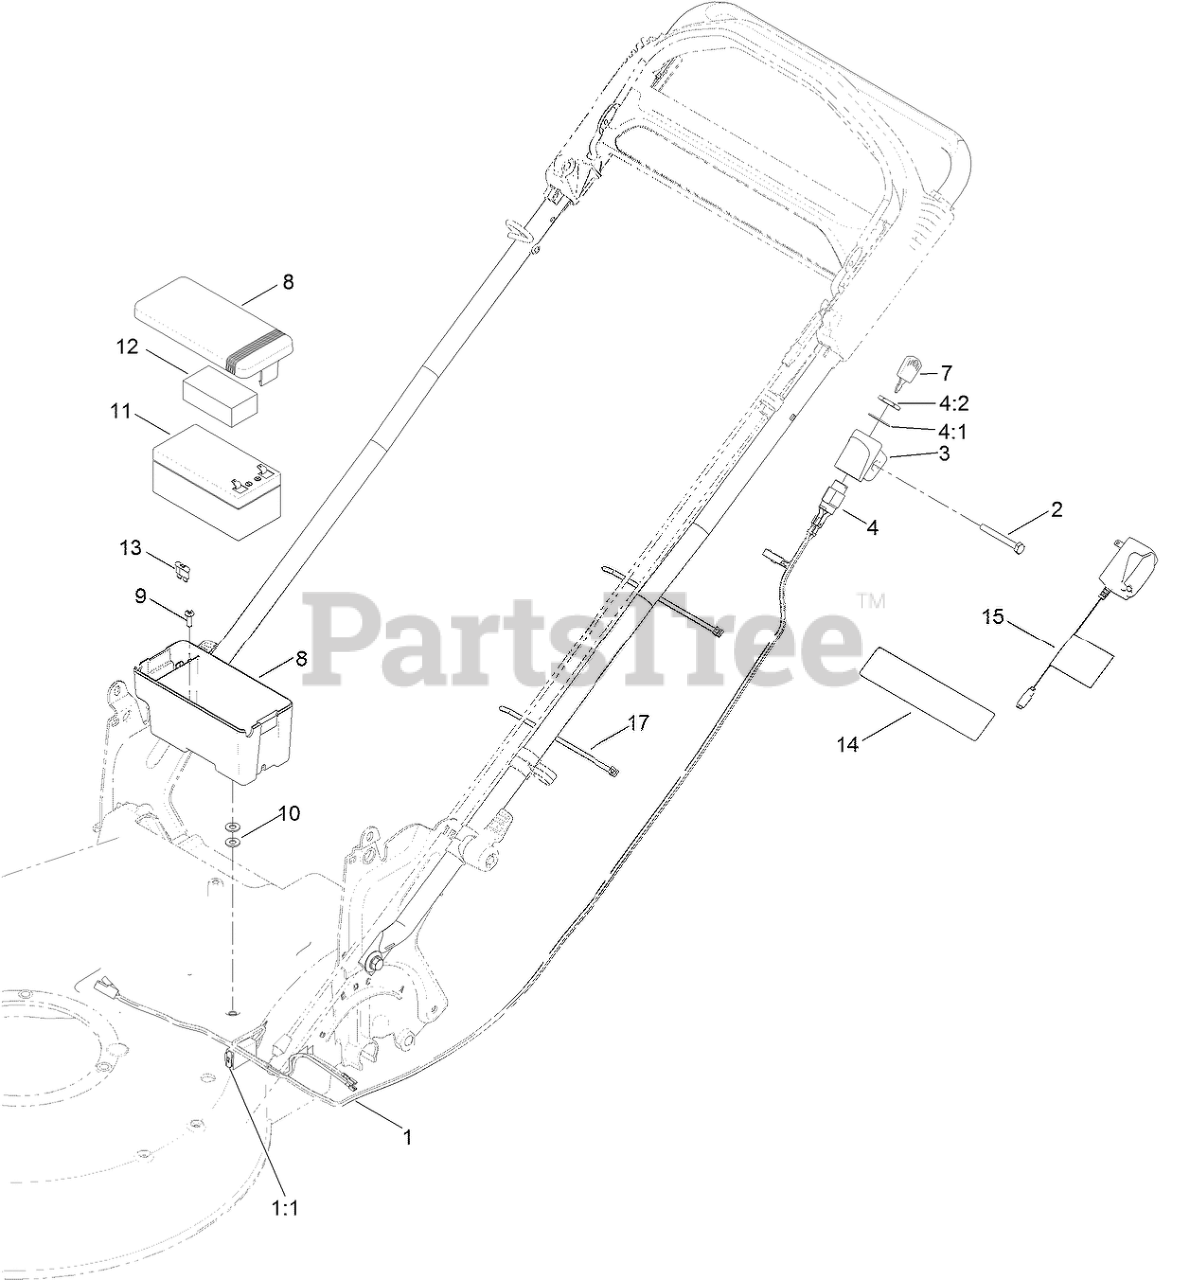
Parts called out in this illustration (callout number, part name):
1	HARNESS-WIRE
1:1	FUSE-40 AMP
2	SCREW-HH
3	MOUNT-SWITCH
4	STARTER SWITCH ASM
4:1	WASHER-TOOTH, INTERNAL
4:2	NUT-HH
8	BATTERY BOX ASM
10	WASHER-FLAT
11	BATTERY-WET
12	FOAM-BATTERY, TOP
13	FUSE-40 AMP
14	DECAL-WARNING
15	CHARGER-CE
17	TIE-CABLE
